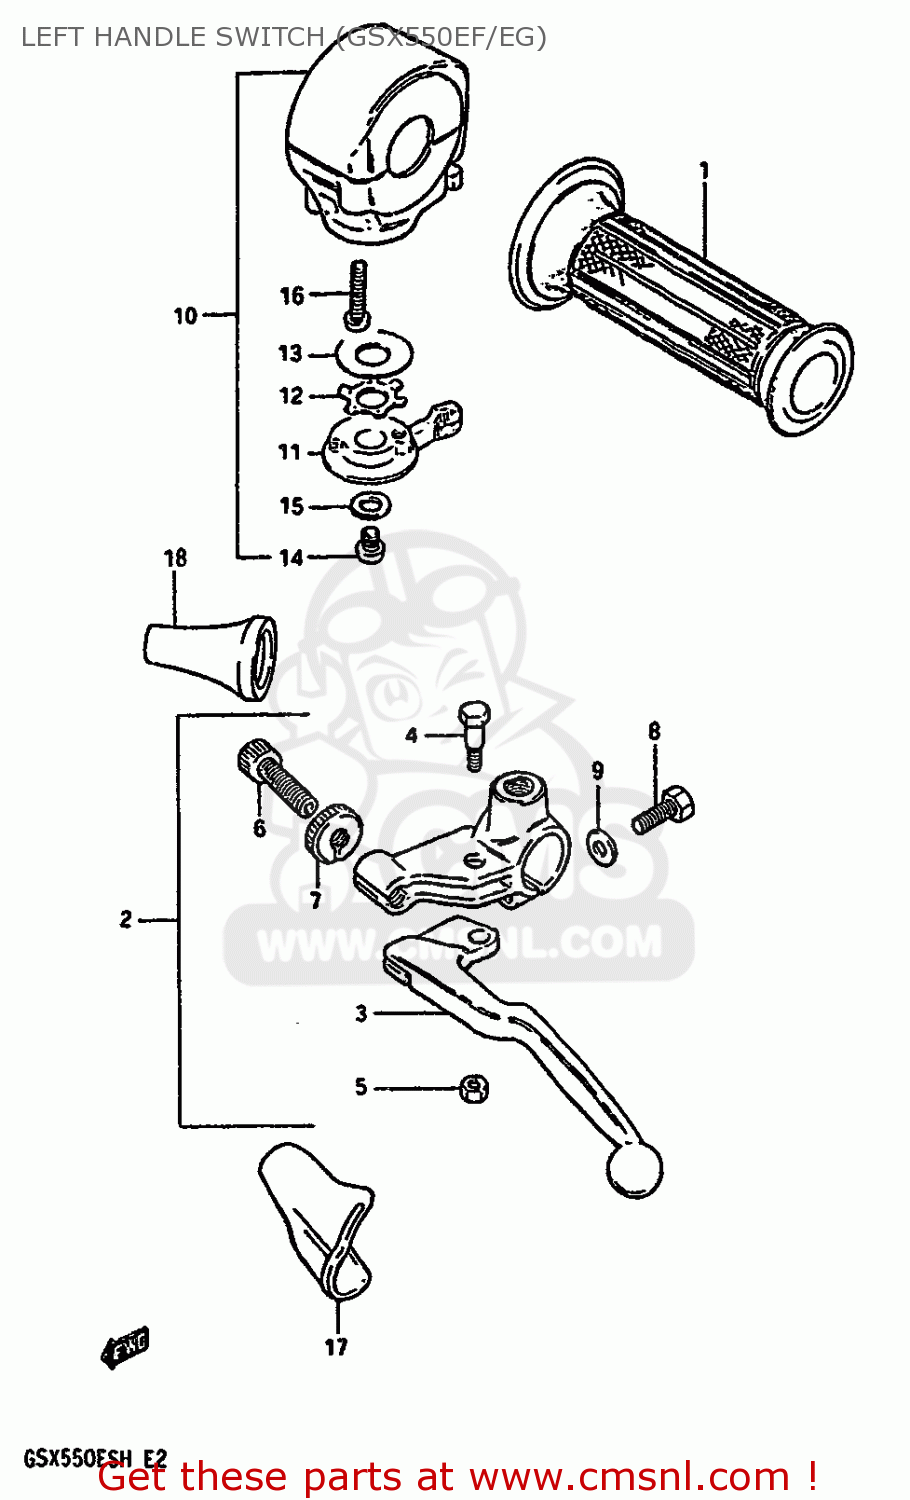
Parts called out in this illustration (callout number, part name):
1	GRIP,L
2	LEVER ASSEMBLY,CLUTCH
3	LEVER,CLUTCH
4	BOLT,LEVER PIVOT
5	NUT
6	ADJUSTER,CABLE
7	NUT,CABLE ADJUSTER LOCK
8	BOLT
9	WASHER
10	SWITCH ASSY,HANDLE LH
11	LEVER,STARTER
12	WASHER
13	WASHER
14	SCREW
15	WASHER
16	SCREW
17	COVER,CLUTCH LEVER
18	BOOT,CLUTCH CABLE
